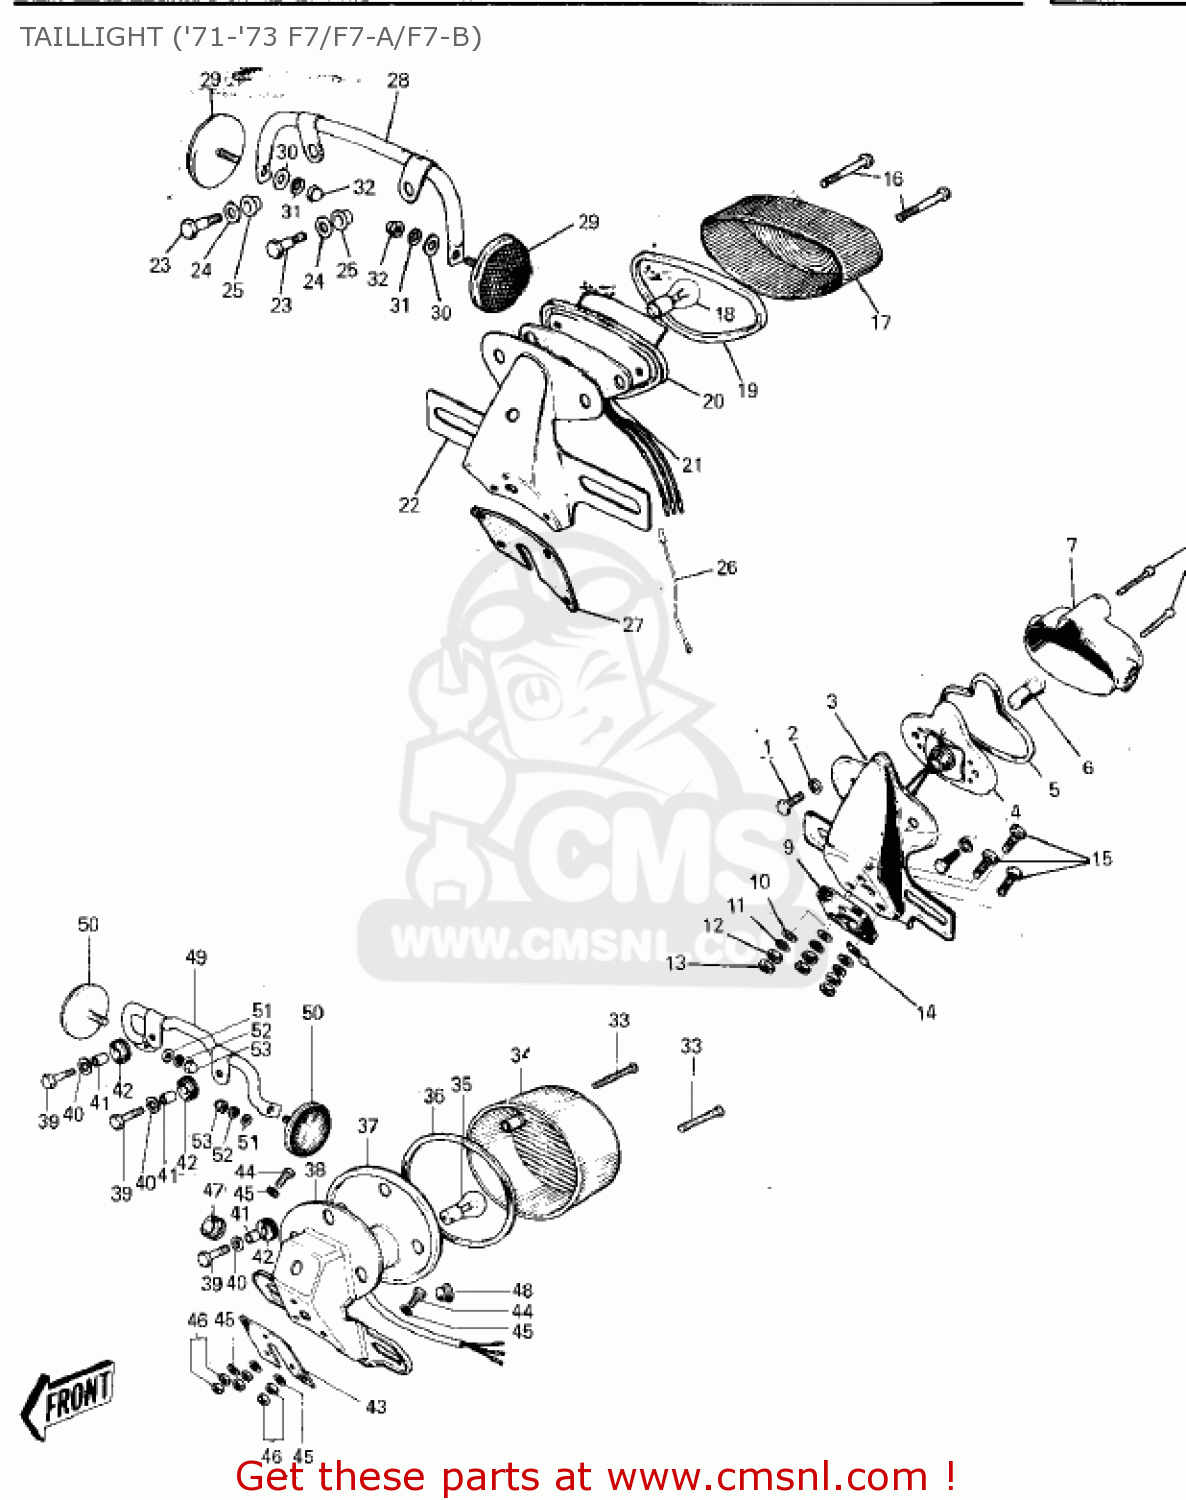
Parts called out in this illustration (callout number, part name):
1	BOLT-HEX HEAD,5X10
2	WASHER-SPRING,5MM
3	BKT-LICENSE PLT,BLACK
4	SOCKET-TAIL LAMP
5	GASKET-TAIL LAMP (NAS)
6	BULB 6V 3/21CP
7	LENS,TAIL LAMP
8	SCREW-PAN HEAD,4X50
9	DAMPER,TAIL LAMP
10	WASHER,6.5X20X1.6
11	WASHER-SPRING,6MM
12	NUT,6MM
13	NUT,6MM
14	CLAMP,WIRING HARNESS
15	BOLT-UPSET,6X35
16	SCREW-PAN-CROS
17	LENS,TAIL LAMP
18	BULB 6V 3/21CP
19	GASKET-TAIL LAMP LENS (NAS)
21	GASKET-TAIL LAMP CASE (NAS)
22	BKT-LICENSE PLT,BLACK
23	BOLT
24	WASHER,8.5X20X1.6
25	DAMPER RUBBER
26	WIRE-IGNITION LEAD
27	DAMPER,TAIL LAMP
28	BRACKET-REFLECTOR
30	WASHER-PLAIN,5MM
31	WASHER-SPRING,5MM
32	NUT-CAP,5MM
33	SCREW-PAN HEAD,4X35
34	LENS,TAIL LAMP
35	BULB 6V 17/5.3W
36	GASKET,TAIL LAMP LENS (NAS)
37	BODY-COMP-TAIL LAMP
38	BKT-LICENSE PLT,BLACK
39	BOLT 6X20
40	WASHER,6.5X20X1.6
41	COLLAR,6.8X10X8.5
42	DAMPER
43	DAMPER,TAIL LAMP
44	BOLT-HEX HEAD,6X25
45	WASHER,6.5X20X1.6
46	NUT,6MM
47	GROMMET,10MM
48	PLUG,FENDER,RR,12X1
49	BRACKET-REFLECTOR
50	REFLECTOR-REFLEX,RR
51	WASHER-PLAIN,5MM
52	WASHER-SPRING,5MM
53	NUT-CAP,5MM
?	CASE-TAIL LAMP
